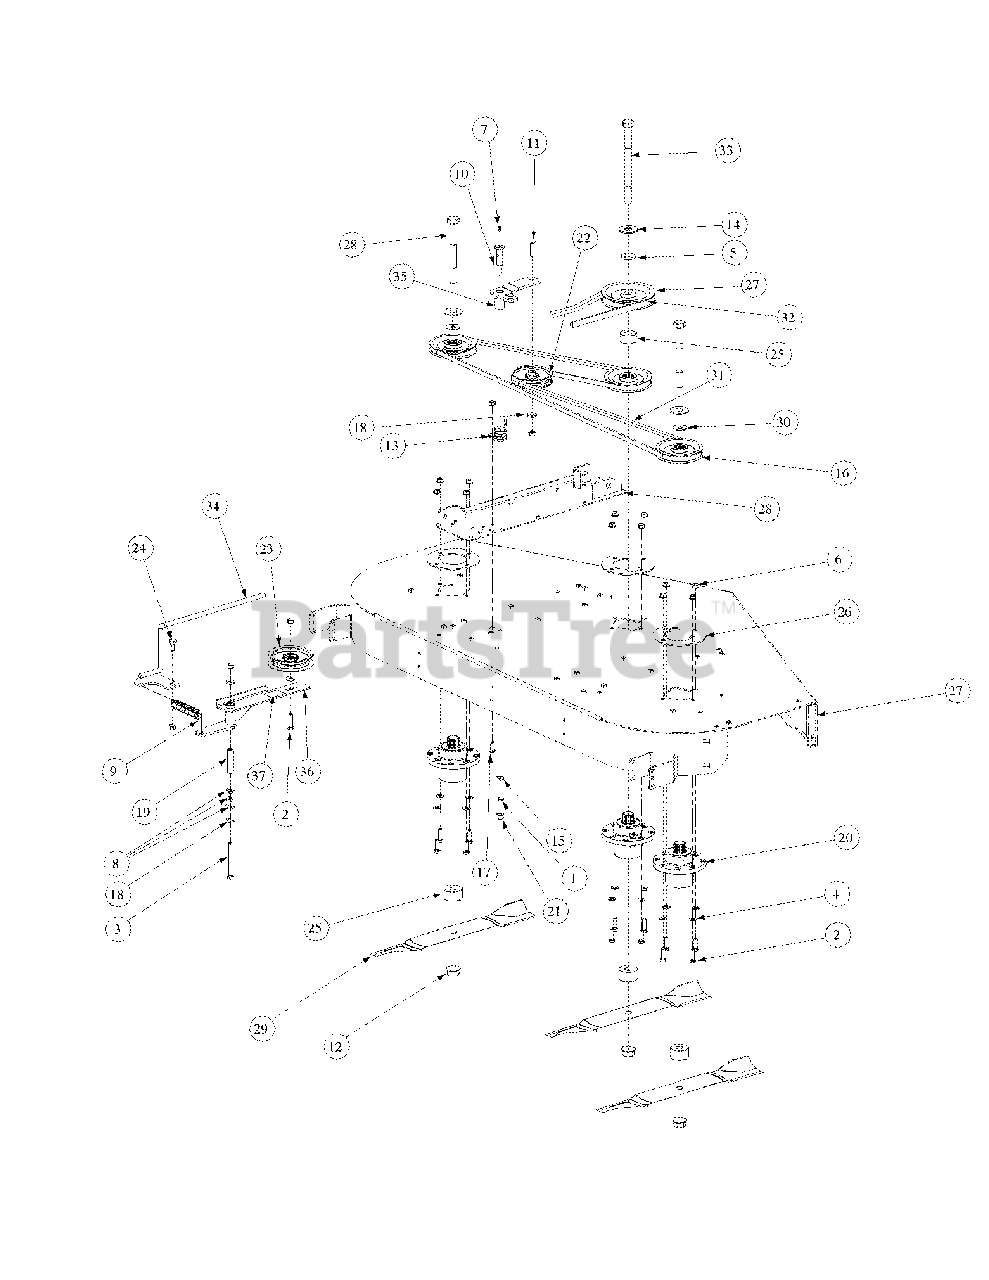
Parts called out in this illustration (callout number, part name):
1	Lock Washer, 7/16
2	Hex Cap Screw, 3/8-16 x 1-1/4
3	Hex Cap Screw, 3/8-16, 4.00
4	Flat Washer, 3/8
5	Caster Spacer
6	Flange Lock Hex Nut, 3/8-16
7	Grease Fitting, 1/4-28 x 3/16
8	Idler Washer
9	Extension Spring, 1.0 x OD x 5.125
10	Shoulder Screw, 7/16-14
11	Hex Carriage Screw, 3/8-16, 1.75
12	Flange Hex Nut, 3/4-16
13	Torsion Idler Spring
14	Flat Washer, .781 ID 2.00 OD, .105
15	Flat Washer, .469 ID, .875 OD, .105
16	V-Pulley, 5.00 OD
17	Carriage Bolt, 3/8-16 x 1
18	Flat Washer, .406 ID, 1.0 OD, .105
19	Spacer, .39 ID x .625 OD x 2.75
20	Aluminum Spindle Assembly
21	Hex Nut, 7/16-14
22	Flat Pulley
23	Idler Pulley, 4.06 OD
24	Shoulder Screw, .50 x .27 Lg., 3/8-16
25	Spacer, .760 ID x 2.00 OD x 1.1
26	Aluminum Spindle Support Plate
27	V-Pulley, 5.774 OD
28	Hex Cap Screw, 3/4-16, 7.00
29	Hi-Lift Blade, 21.0, 0.756 ID
30	Spacer .812 ID x .268 LG
31	V-Belt, A Section x 122.3
32	V-Belt, B Section x 91.2
33	Hex Cap Screw, 3/4-16, 9.00
34	Spring Tension Rod Assembly
35	Idler Arm Assembly, Deck Spindle
36	Idler Arm Assembly, Flat Top Bearing
36	Bearing Sleeve
37	Decal, Idler Location
